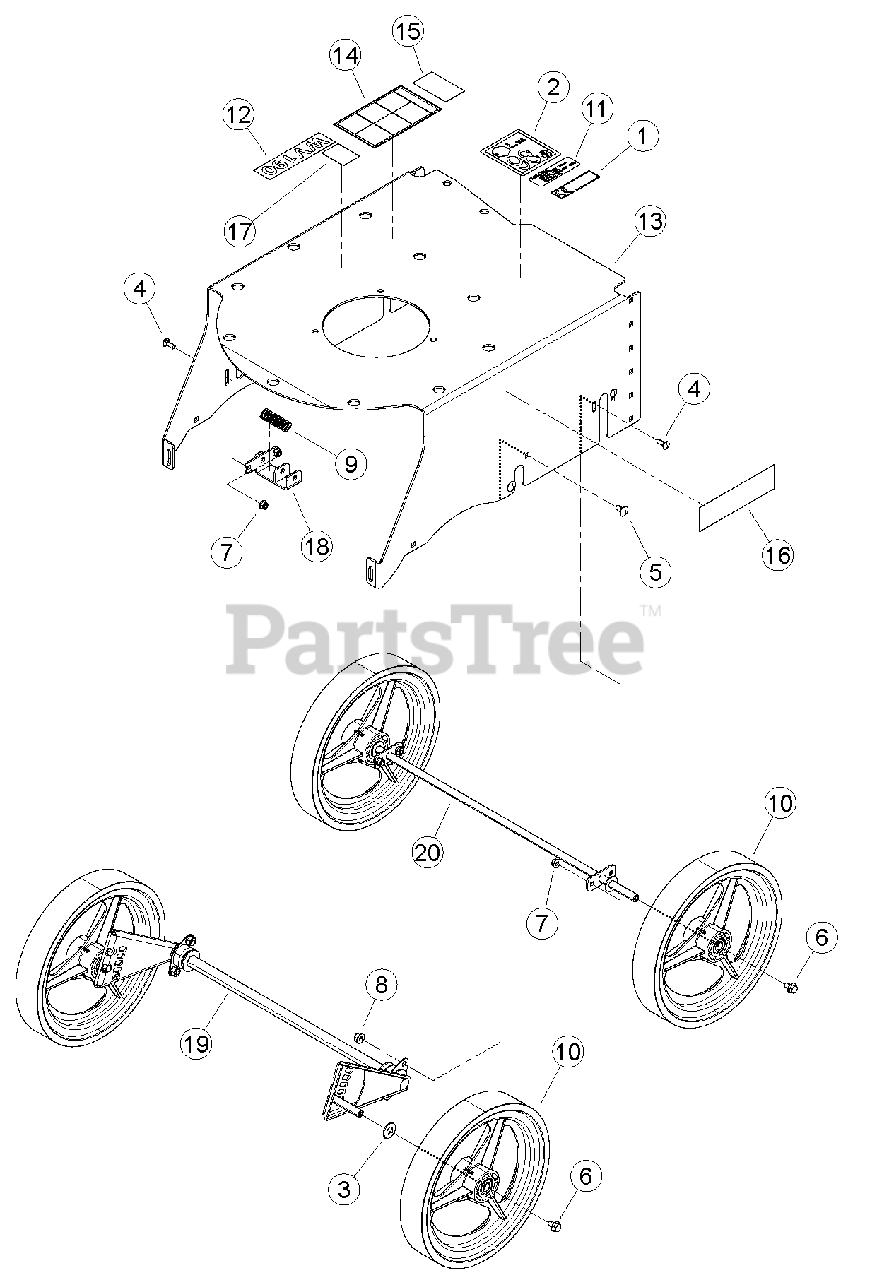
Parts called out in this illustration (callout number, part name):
1	DECAL, 6HP PUSH BEARVAC INFORMATION
2	DECAL, 98 DB (WV190 ONLY)
3	WASHER, 1/2 SAE FLAT
4	BOLT, 1/4 X 3/4 GR5 CRG ZP
5	BOLT, 5/16 X 5/8 GR5 CRG ZP
6	BOLT, 5/16-18 X 1/2 G5 HH SR/FLN
7	NUT, 1/4-20 NYLOCK-FLANGE
8	NUT, 5/16-18 NYLOCK-FLANGE
9	SPRING, LC-072J06S COMPRESSION
10	ASSEMBLY, WHEEL BEARVAC PUSH
11	DECAL, ATLANTIC BRIDGE LTD INFO (WV190 ONLY)
12	DECAL, MODEL WV190
13	ASSEMBLY, PUSH VAC HOUSING W/ DECALS
14	DECAL, OPERATING INSTRUCTIONS ISO
15	DECAL, DANGER
16	DECAL, ECHO BEARCAT 6.82 X 1.90
17	DECAL, ECHO BEARCAT QR CODE
18	WELDMENT, BEARVAC HEIGHT ADJ.
19	WELDMENT, AXLE PIVOT
20	WELDMENT, AXLE BEARVAC PUSH
